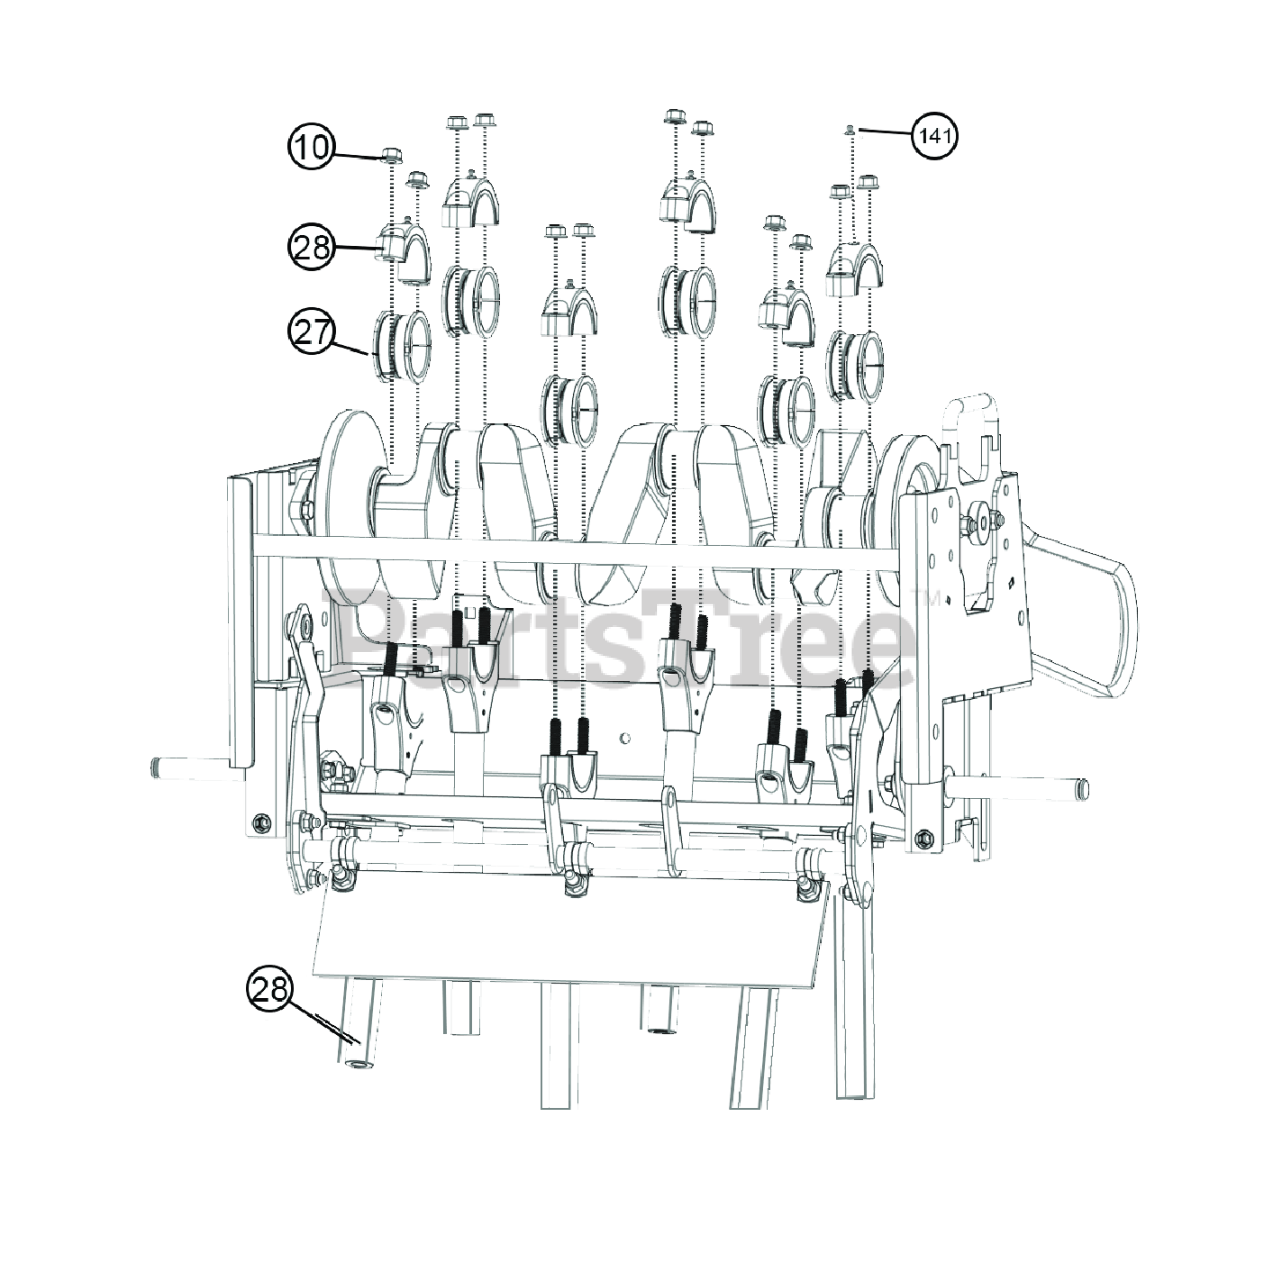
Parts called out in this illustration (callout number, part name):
10	NUT-HEX-NYLK, FLG .375"-16 ZP
27	BEARING JOURNAL 2" DIA
28	ASM, TINE ROD AND CAP
141	ZERK, GREASE STR .250"-28 X .359" TPR
